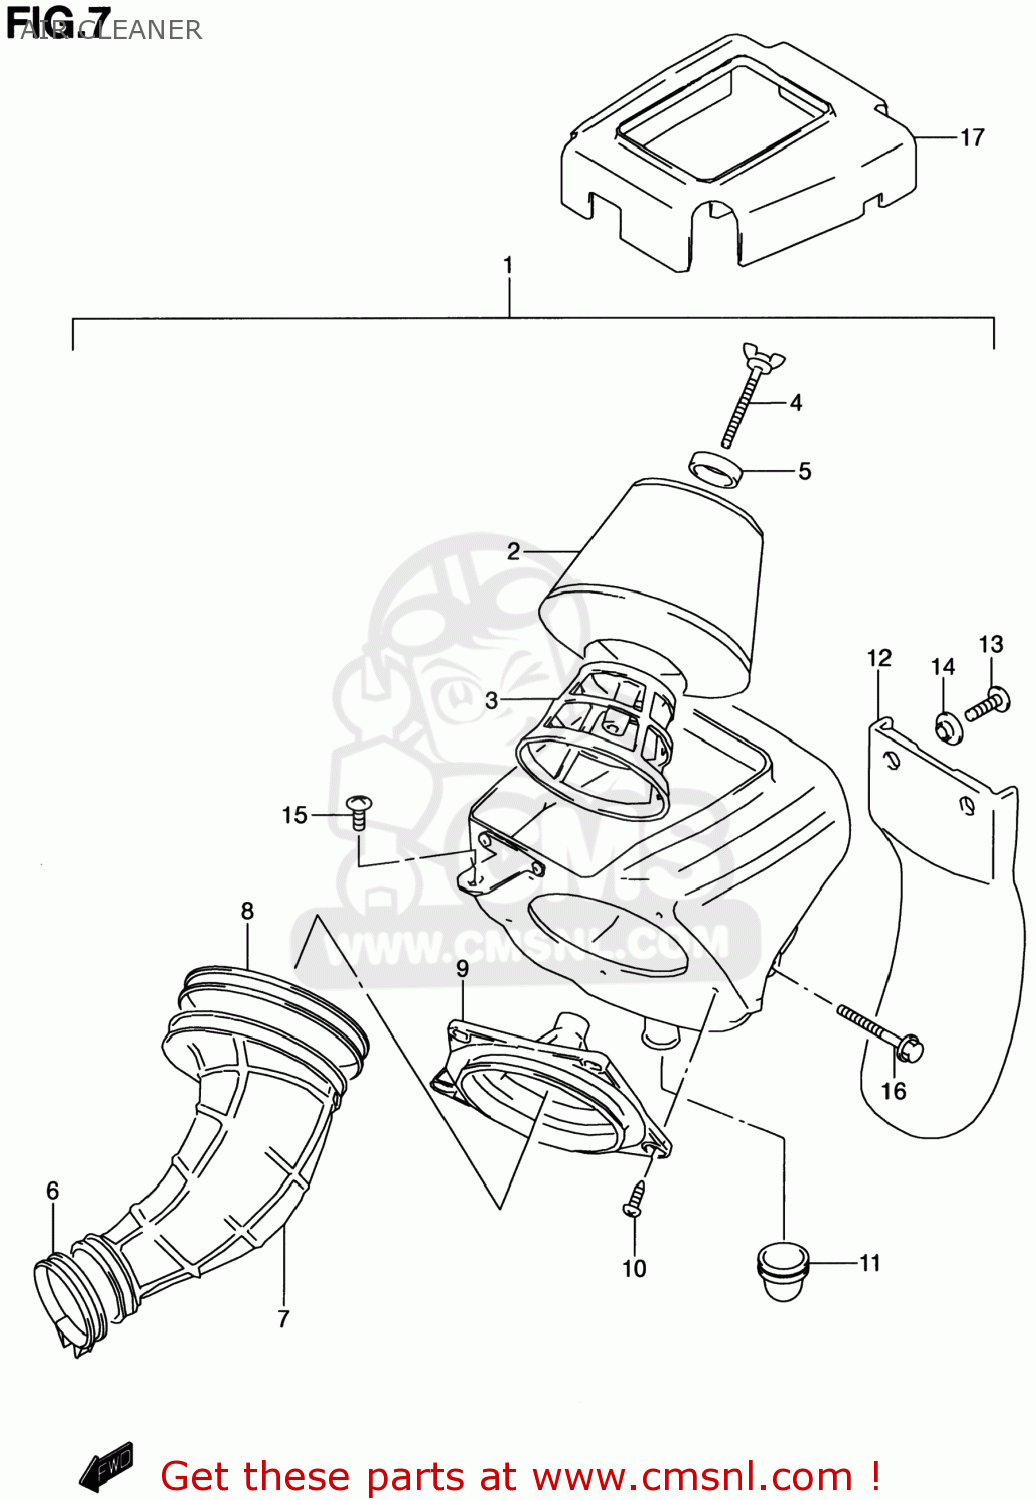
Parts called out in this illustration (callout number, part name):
1	CLEANER ASSY,AIR
2	FILTER ASSY
3	HOLDER
4	BOLT,WING
5	WASHER,AIR CLEANER
6	CLAMP
7	TUBE,OUTLET
8	CLAMP
9	BASE,FILTER
10	SCREW
11	HOSE,AIR CLEANER DRAIN
12	GUARD,MUD
13	SCREW
14	COLLAR
15	SCREW 6X12
16	BOLT
17	MUD GUARD,B
